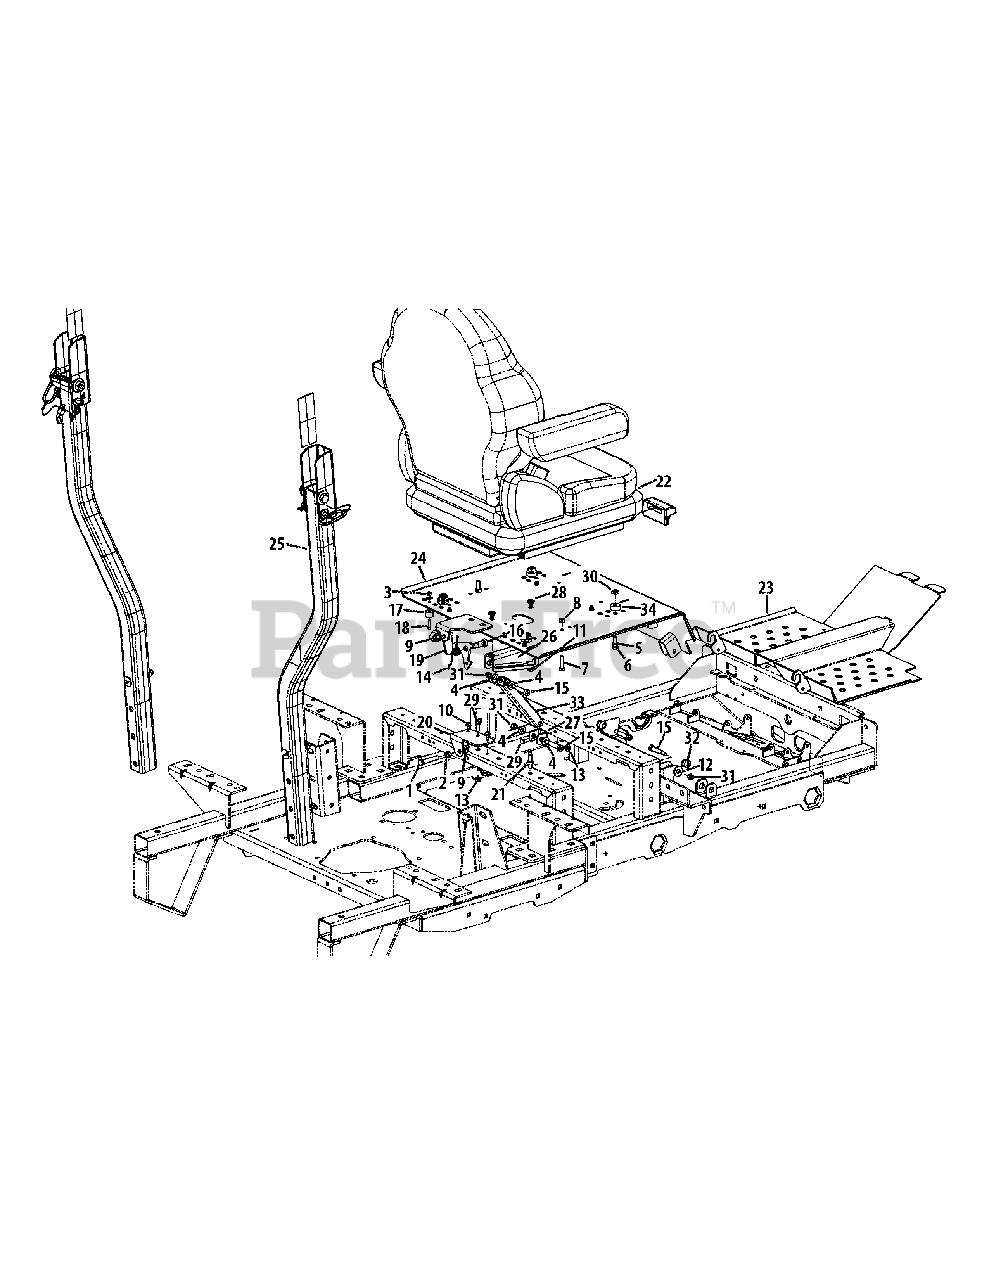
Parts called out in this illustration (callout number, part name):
1	Hex Screw, 3/8-16 x 2.00
2	Nut, 3/8-16
3	Nylock Nut, #10-24
4	Wsdher, .406 x .813 x .063
5	Lock Washer, .312 x .583 x .083
6	Hex Screw, 5/16-18 x 1.00
7	Hex Screw, 5/16-18 x 1.25
8	Counter Lock Nut, 5/16-18
9	Flange Counter Lock Nut, 3/8-16
10	Hex Screw, 1/4-20 x .500
11	Flange Counter Lock Nut, 5/16-18
12	Washer, .406 x 1.00 x .105
13	Flange Top Lock Nut, 1/4-20
14	LH Torsion Spring, .725 x 1.07 x .09
15	Shoulder Bolt, 5/16-18 x .37 x 1.50
16	Shoulder Bolt, 3/8-16 x .50 x .75
17	Bump Stop w/ Washer
18	Flat Head Screw, #10-24 x .750
19	Lever Latch Bracket
20	Mount Latch Bracket
21	Center Adjust Stud, .375 x 1.125
22	Suspension Seat w/ Seat Belt
23	Wide Assembly Floor Panel
24	Seat Mount Bracket Assembly
25	Folding ROPS Assembly
25	Bracket - Hinge Rops
25	Bumoer - Grommet Rops
26	Seat Support Lock Bracket
27	Seat Link Pivot Mount Bracket
28	Carriage Bolt, 5/16-18 x .62
29	Hex Screw, 1/4-20 x .75
31	Hex Lock Nut, 5/16-18
32	Grommet, .38 x .75 x .75
34	Spacer, .406 x 1.00 x .38
